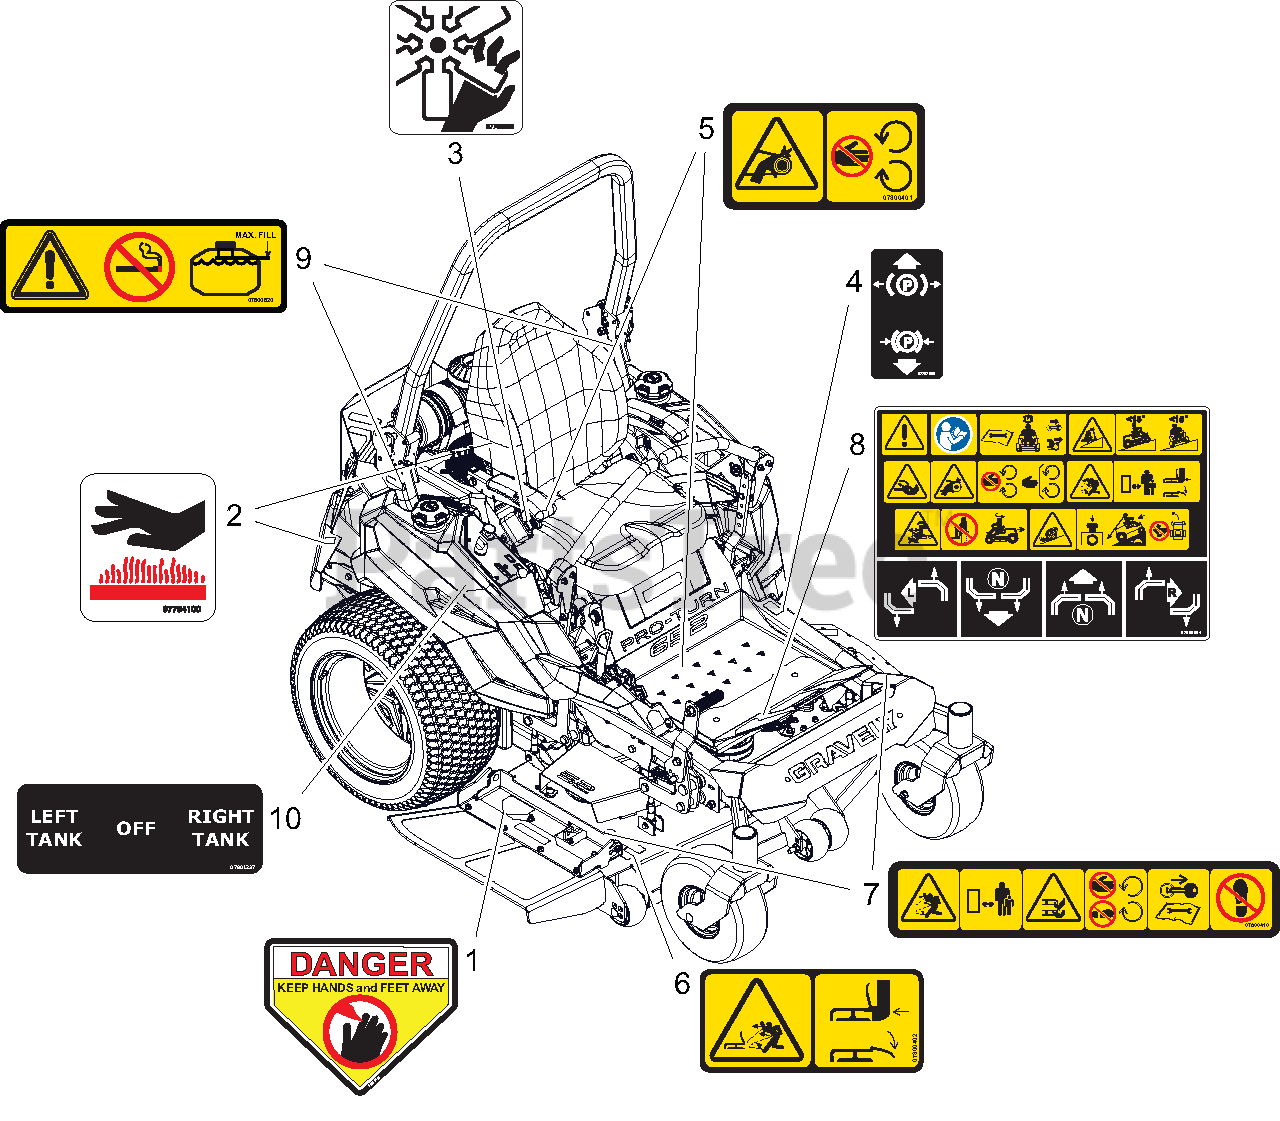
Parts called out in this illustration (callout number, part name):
1	DECAL, DANGER
2	DECAL, HOT SURFACE
3	DECAL, DANGER FAN
4	DECAL, PARKING BRAKE LEVER
5	DECAL, SAFETY - GUARDING
6	DECAL, SAFETY - DECK GUARDING
7	DECAL, DECK SAFETY
8	DECAL, INSTR SAFETY
9	DECAL, FUEL WARNING
10	DECAL, FUEL VALVE
